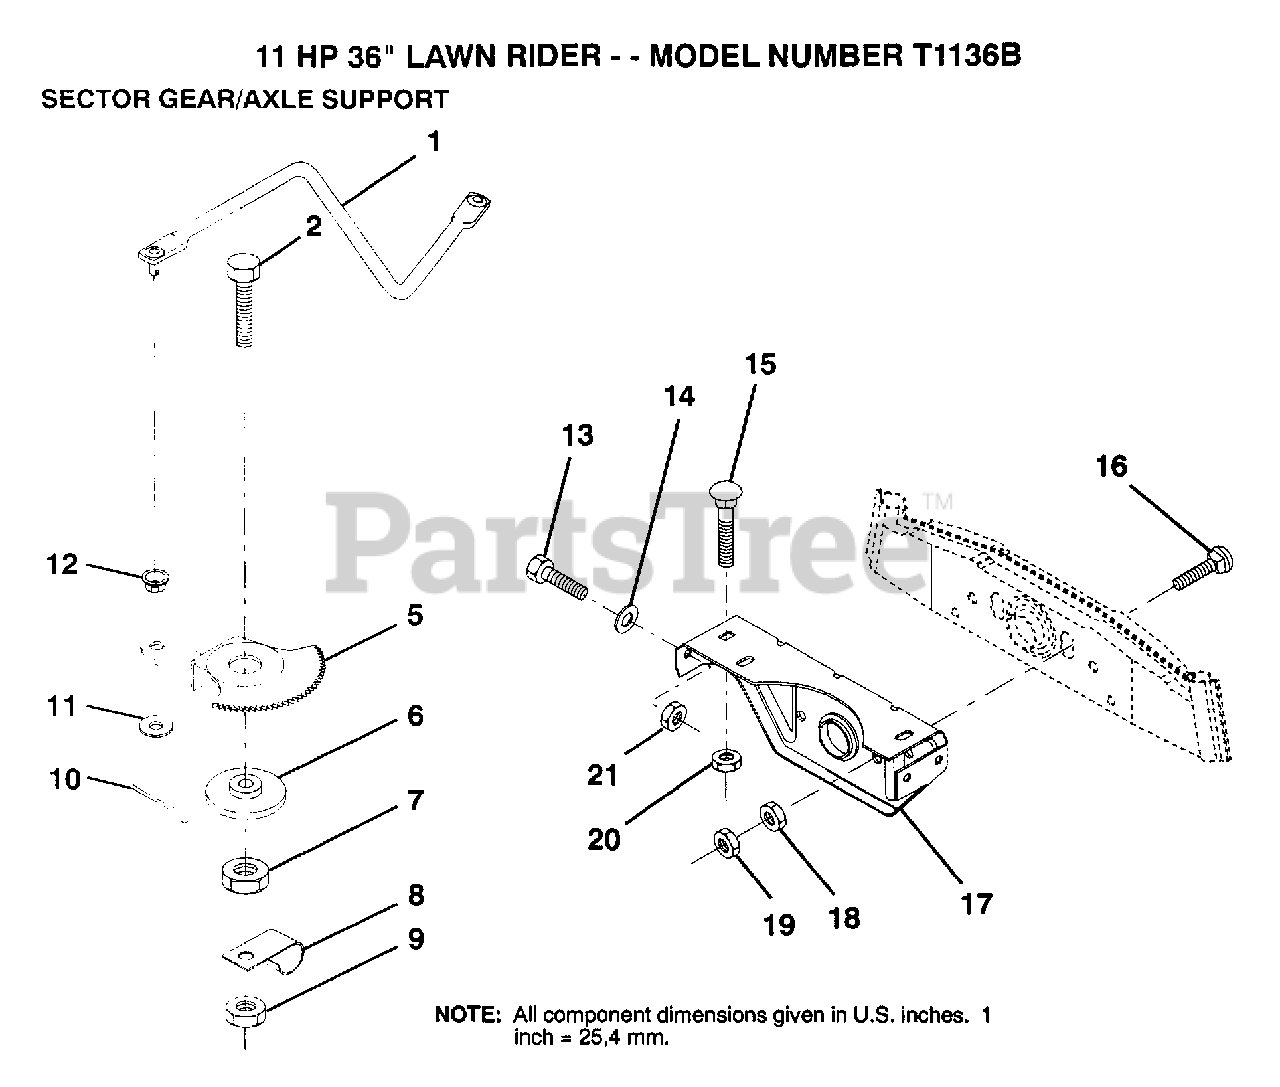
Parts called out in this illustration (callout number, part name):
1	DRAG LINK
2	"BOLT,HEX"
5	GEAR SECTOR
6	BUSHING
7	NUT
8	CLIP INSULATOR
9	NUT LTV
10	COTTER PIN
11	WASHER
12	BUSHING.DRAGLINK
13	BOLT
14	WASHER
15	BOLT
16	BOLT
17	"SUPT,FRT AXLE"
18	NUT.HEX.3/8-16UNC
19	LOCKNUT
